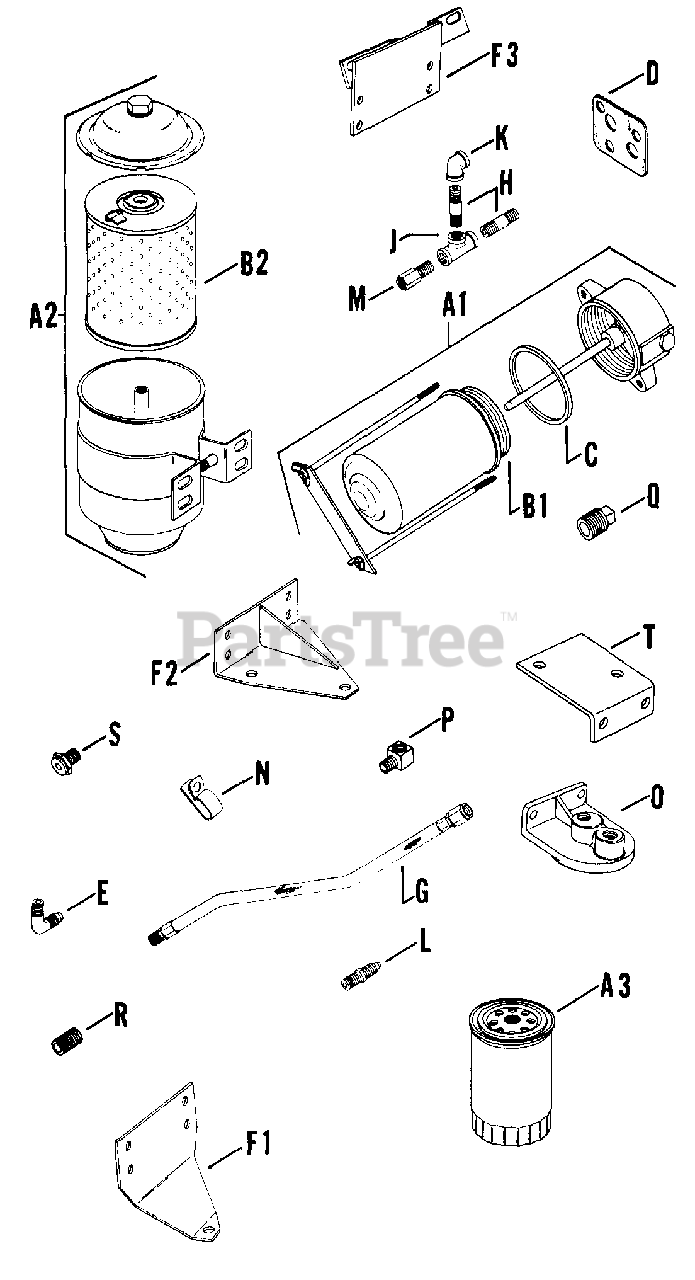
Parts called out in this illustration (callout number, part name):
A2	Filter, oil - assembly (Includes B2)
B2	ELEMENT - DISCONTINUED
G	LINE - DISCONTINUED
H	NIPPLE, PIPE 1/8 X 3/4 USE 25 136 23-S
J	TEE - DISCONTINUED
J	Tee, pipe
M	Restriction
Q	PLUG, PIPE USE 25 139 52-S
